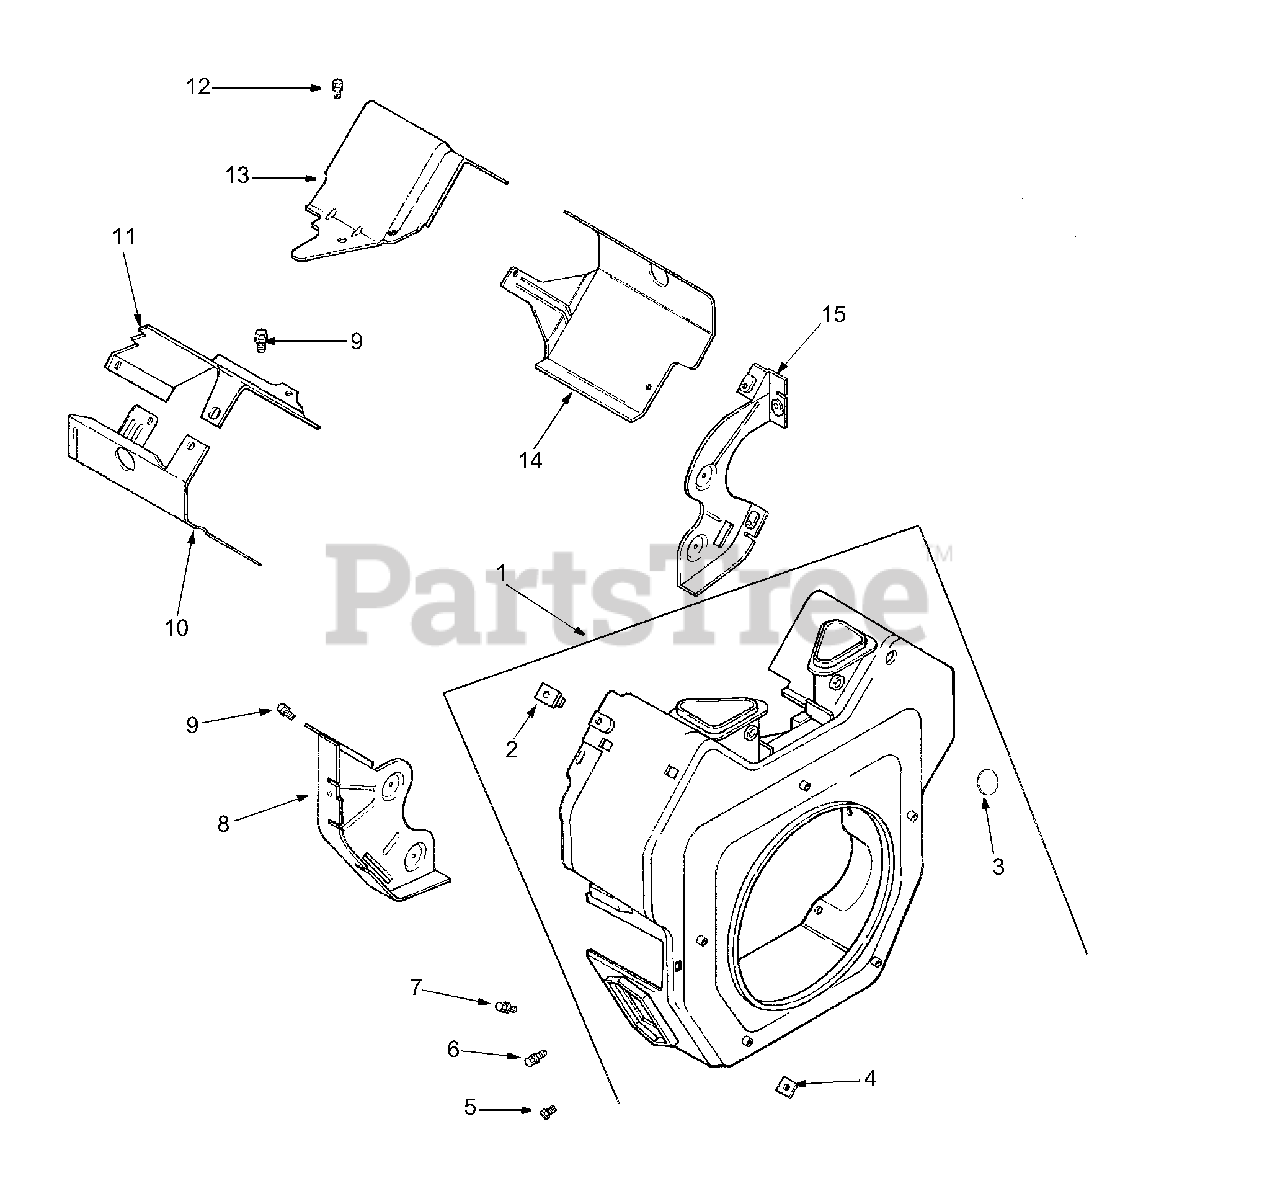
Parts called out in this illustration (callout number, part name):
1	Housing, Blower
2	Nut, Plastic
3	Plug, Button 9/16"
4	Nut, Plastic
5	Screw, Hex Flange M5 x 0.8 x 16
6	Screw, Hex Flange M5 x 0.8 x 16
7	Screw, Hex Flange M5 x 0.8 x 20
8	Plate, Backing #2 Side
9	Screw, Hex Flange M6 x 1.0 x 16
10	Baffle, Cyl. Barrel #2 Side
11	Baffle, Valley #2 Side
12	Screw, Hex Flange M5 x 0.8 x 10
13	Baffle, Valley #1 Side
14	Baffle, Cyl. Barrel #1 Side
15	Plate, Backing #1 Side
